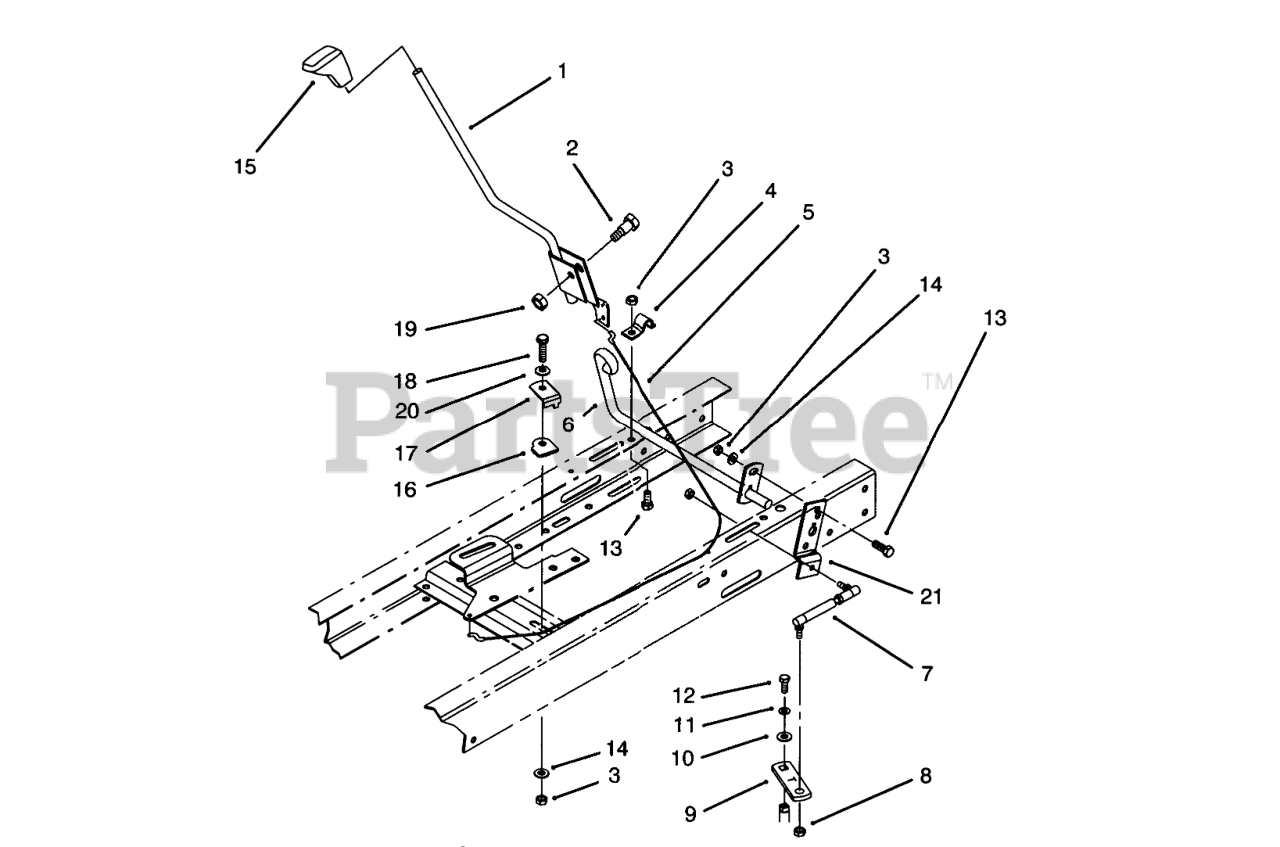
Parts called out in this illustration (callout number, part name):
1	Lever-Shift
2	SHOULDER BOLT
3	NUT-LOCK, NI
4	CLAMP-PIVOT, SHIFT
5	CABLE-CLUTCH
6	SHIFT PIVOT WAB
7	TIE ROD, SHIFT
8	NUT-LOCK
9	LEVER-SHIFT
10	SPACER
11	WASHER-LOCK
12	SCREW-HH
13	SCREW-HH
14	WASHER-PLAIN
15	SHIFT KNOB
16	GUIDE-CABLE
17	KEEPER-CABLE
18	SCREW-CARR
19	NUT-LOCK, NI
20	WASHER-FLAT
21	SHIFT LEVER PIVOTB
